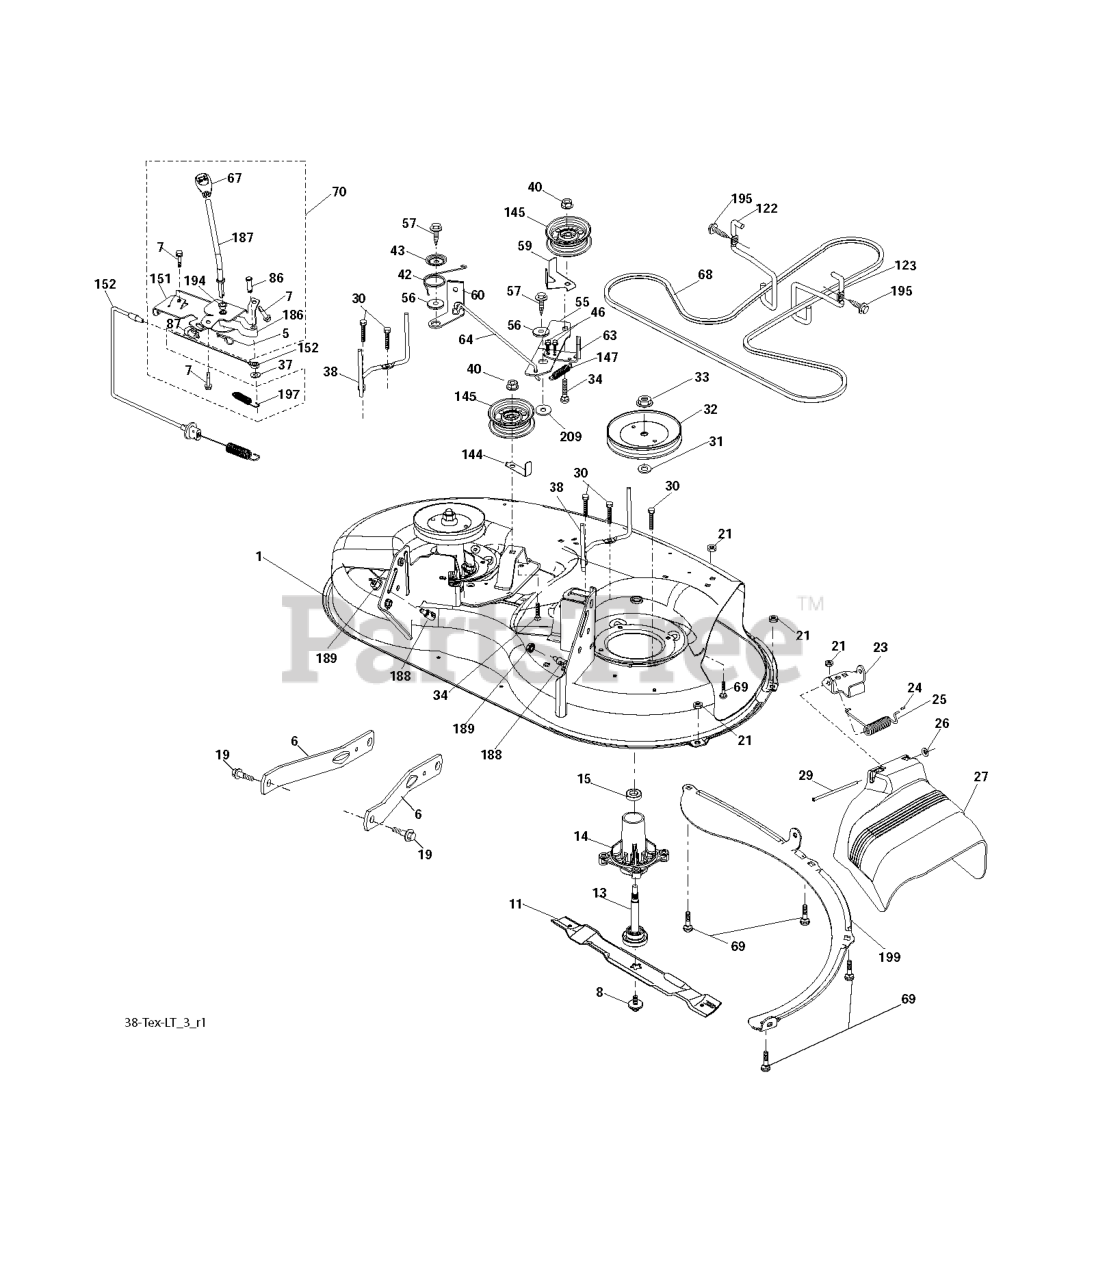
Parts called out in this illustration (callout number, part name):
1	HOUSING
5	RETAINER-SPRNG RB
6	ARM.SUSPENSION.MOWER.R
7	SCREW
8	BOLT.WASHER.ASM.7/16-2
11	BLADE 38" PREMIUM
13	SHAFT.ASM.MDRL.N/GREASE.38
14	RP.HOUSING.MANDREL.4PT.
19	BOLT.SHOULDER
21	LOCKNUT
23	BRKT.DEFLECTOR.38"2005+
24	CAP-SLEEVE LT
25	SPRING.TORSION.DEFLECT
26	NUT PUSH M
27	SHIELD.DEFLECTOR.MWR.38-7/97CM
29	ROD.HINGE
30	SCREW, WASHER HEAD
31	WASHER.SPACER.MANDREL
32	PULLEY.MANDREL.5.0.PD.38"
33	NUT.FLANGE.LOCK.TOP
34	BOLT.3/8-16X1.50
37	WASHER
38	KEEPER BELT LH MANDREL
40	NUT LOCK FLG 3/8-16 UNC
42	SPRING.TORSION.BRAKE
43	SRPING.TORSION.RETAINE
46	SCREW.1/4-20X5/8
56	SPACER.RETAINER
57	SCREW 3/8-16X1
59	GUARD, BELT
60	ARM BRAKE MOWER RH 38"
63	RP ARM.BRAKE.MOWER.38"LH.TEX
64	LINK BRAKE
67	HANDLE.CLUTCH.CABLE.LT
69	BOLT
70	CLUTCH.ASM.MANUAL.LT.PRED
86	PIN ATTACHMENT CABLE
87	SWITCH.INTRLCK.CLUTCH.
122	KEEPER BELT ENGINE LH
123	KEEPER BELT RH
144	KEEPER, BELT IDLER
145	PULLEY.IDLER.48"PRIMARY
147	SPRING RETURN
151	BRACKET.CLUTCH CBL.PRED LT
152	CLUTCH CABLE
186	ARM ACTUATOR
187	LEVER.CONTROL.CL.CABLE.PRED LT
188	STUD.FASTNER.W/ANTI-ROTATE
189	NUT LOCK HEX FLANGE 5/16-18
194	BEARING.CONTROL.LEVER.CLUTCH
195	SCREW, 3/8-16X3/4
197	SPRING.PLUNGER.ACTUATOR
199	BAFFLE.VORTEX.FRONT.38"
209	WASHER 12/32X2X10GA
